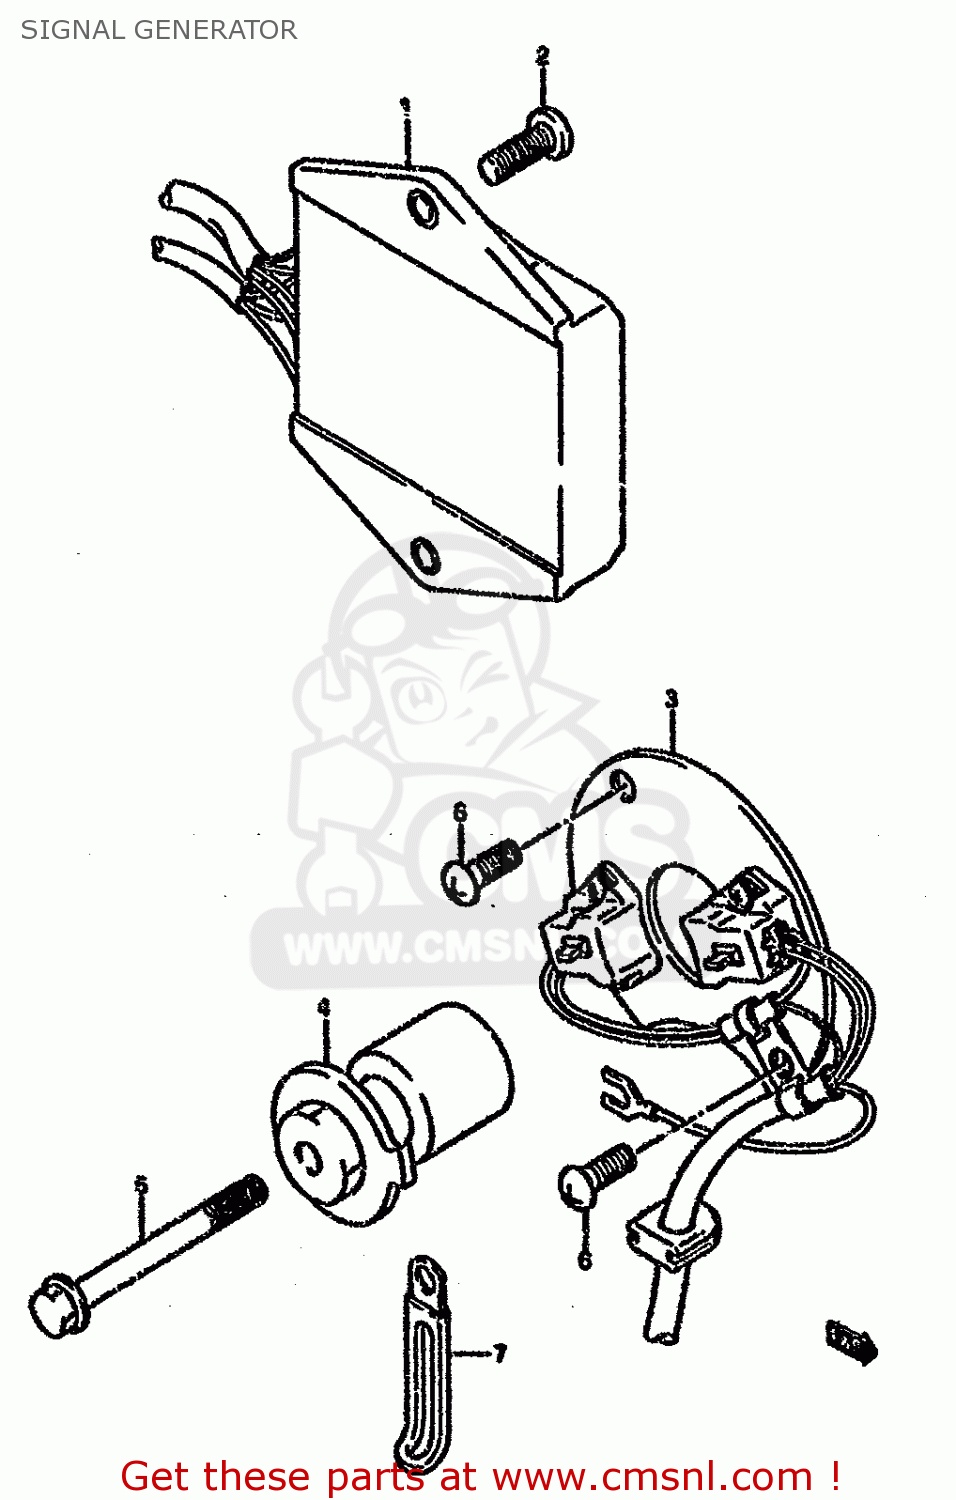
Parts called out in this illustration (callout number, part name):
1	IGNITOR ASSY
2	SCREW
3	SIGNAL GENERATOR ASSY
4	ROTOR,SIGNAL
5	BOLT
6	SCREW
7	CLAMP
